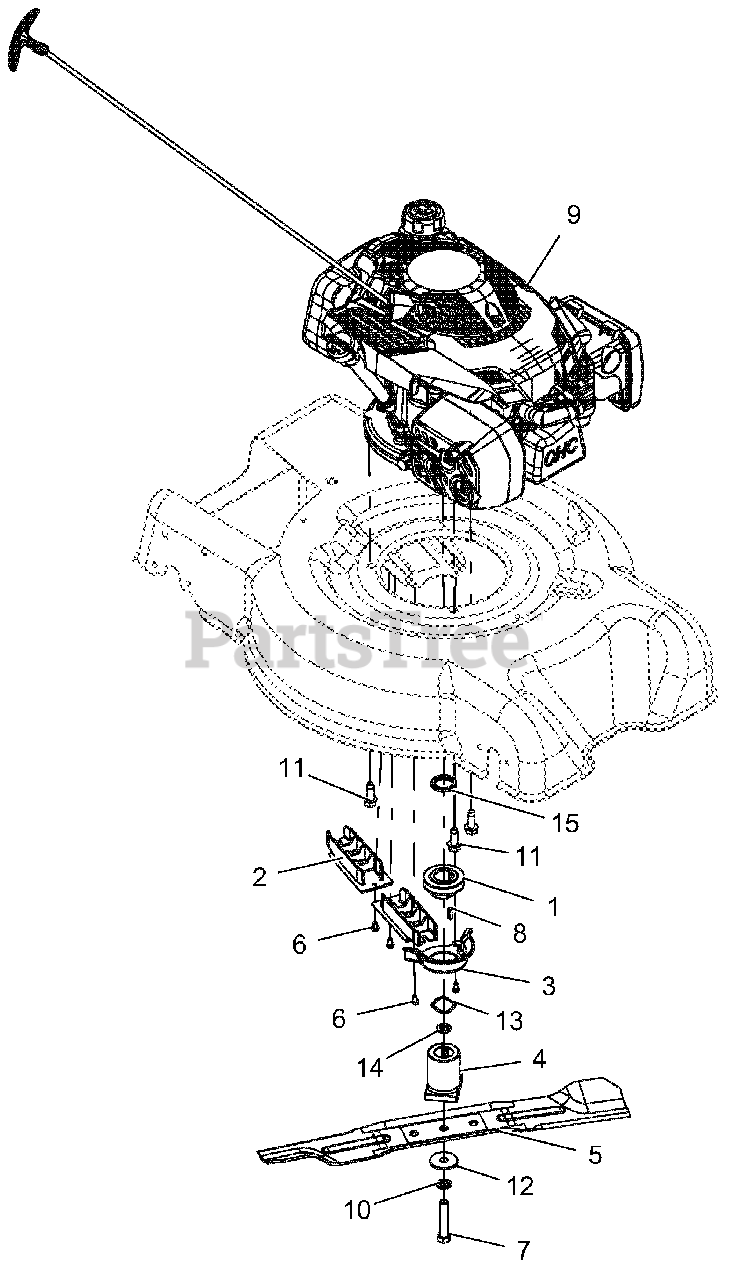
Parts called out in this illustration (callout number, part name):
1	PULLEY, GROUND DRIVE, LM
2	GUIDE, BELT INNER
3	GUIDE, BELT CRANK
4	ADAPTER, BLADE
5	BLADE, MOWER 21" HIGH LIFT
6	SCR-TAP 10-24X.375 PRE-COAT 80
7	@BLT-HEX .4375-20X2.25 GR8 YWZ
8	KEY-SQ .188X.188X.625
9	ENGINE, SUBARU 175CC VERT. ES
10	@WSHR-LK .44X.109 REG YWZC
11	@SCR-TAP .38-16X1.00 HWH TR YZ
12	WSHR-FL-STL .4375X1.50X.125 YZ
13	WASHER - WAVE 1.09X1.37X.016
14	WSHR-FL-STL .459X.750X.105 YZC
15	SPCR, 1.00 X 1.375 X .179
